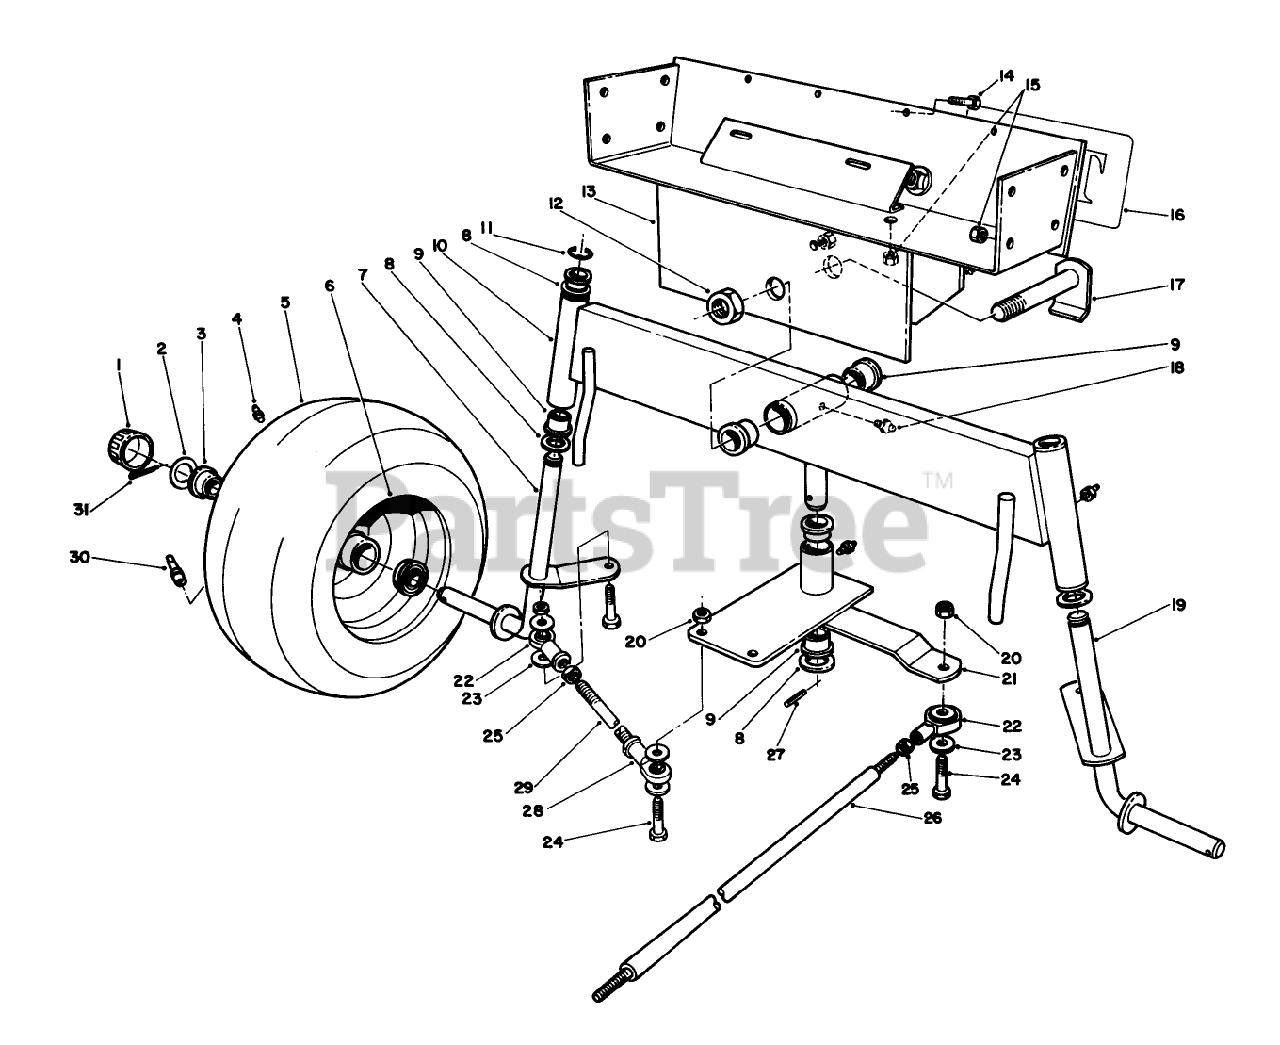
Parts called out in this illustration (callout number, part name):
2	WASHER-PLAIN
4	FITTING-GREASE
8	WASHER-THRUST
9	BEARING-FLANGE
11	E-RING
12	NUT-HEX
14	SCREW-HH
15	NUT-LOCK, NI
18	GREASE FITTING
20	NUT-HEX
22	BALL JOINT RH
23	WASHER-FLAT
24	SCREW-HH
25	NUT-JAM
27	PIN-SPRING
28	BALL JOINT LH
29	TIE ROD - STEERING
31	PIN-COTTER
